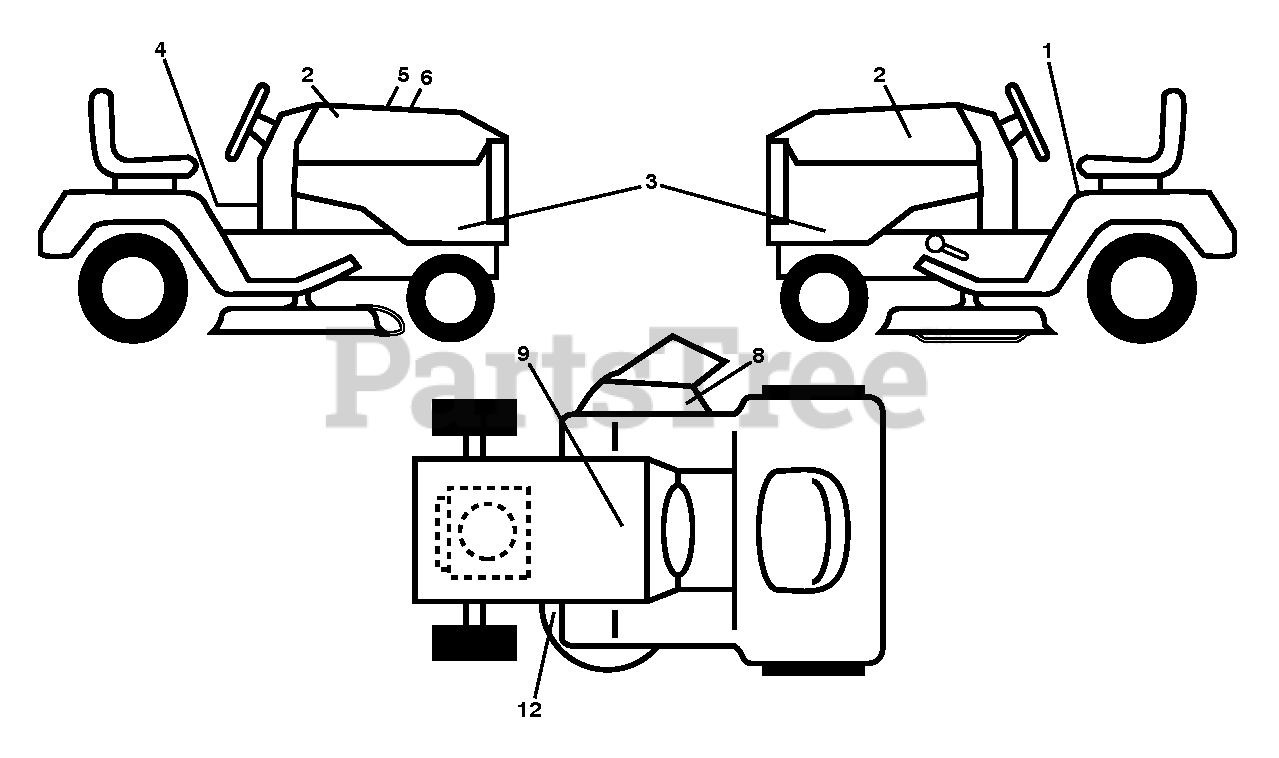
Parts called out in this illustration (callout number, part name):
1	DECAL.FENDER.WARNING.ENGLISH
2	DECAL.BADGE.170MM.TEXTLOGO.
3	DECAL.SIDE.PANEL.YTH18K46
4	DECAL, WARNING SPARK ARRESTOR
5	DECAL.WARNING.CUST.RESP.E85.
6	DECAL.RPL.KW.FR600.TLW.46.K46
8	DECAL.MOWER.WARN.KEEP.HAND.AWY
9	DECAL BTRY SYMBOLS
12	DECAL.V-BELT.SCH.42/46"MEC/ELE
